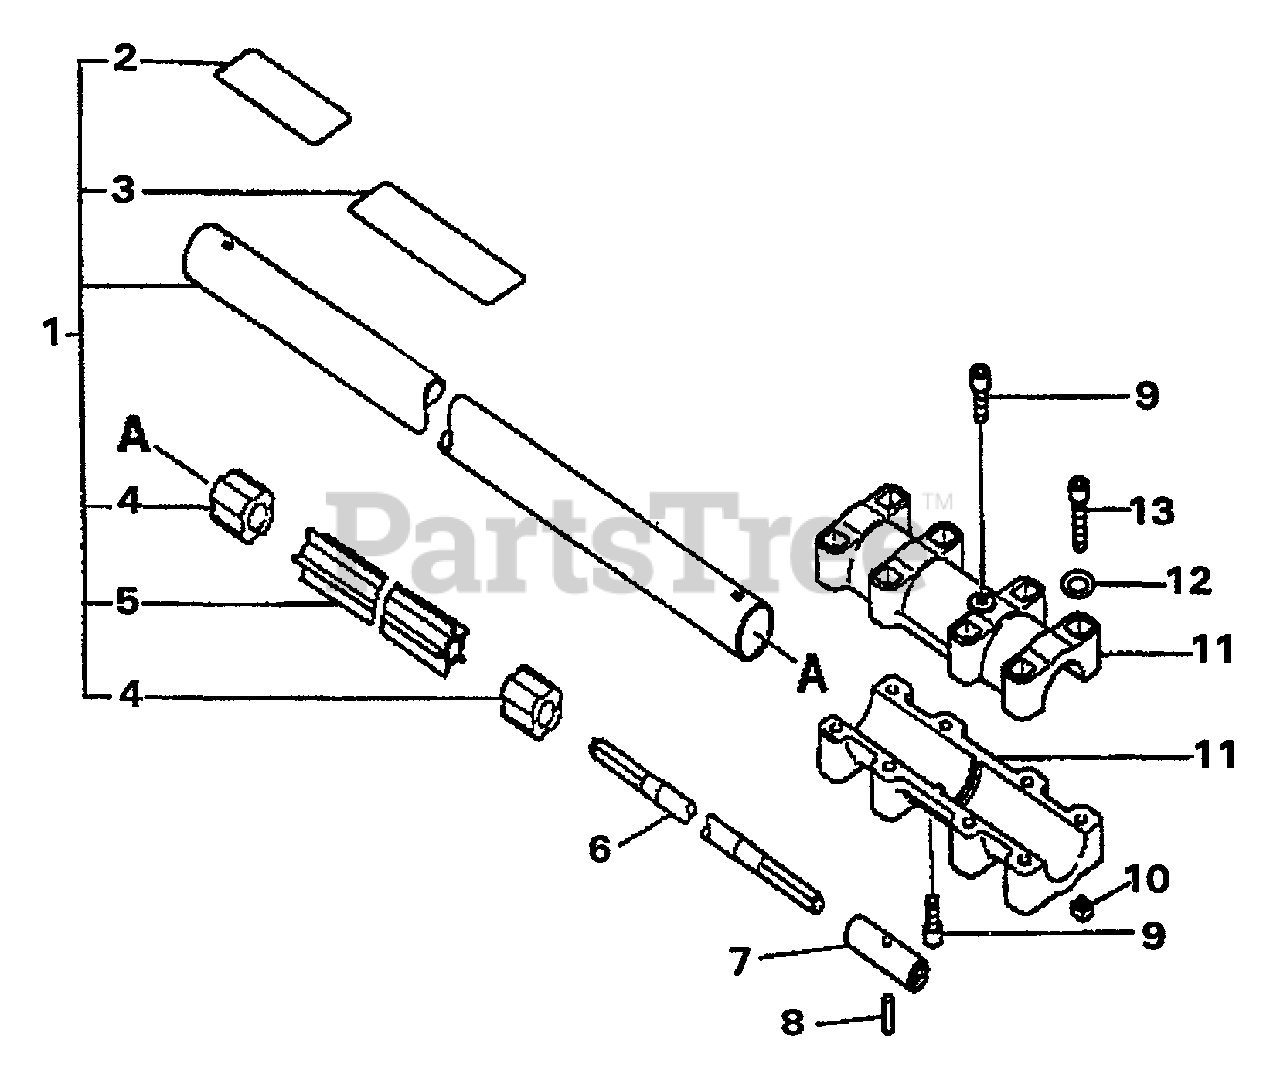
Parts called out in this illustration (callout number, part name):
1	MAIN PIPE ASSY
2	LABEL - CAUTION
3	LABEL - CAUTION
5	LINER - FLEXIBLE
6	DRIVESHAFT - FLEXIBLE
7	CONNECTOR, SHAFT
8	PIN, SPRING 1/8×1/2
9	BOLT 5×14
10	NUT M5
11	HOLDER
12	WASHER, SPRING 5
13	BOLT 5×25
